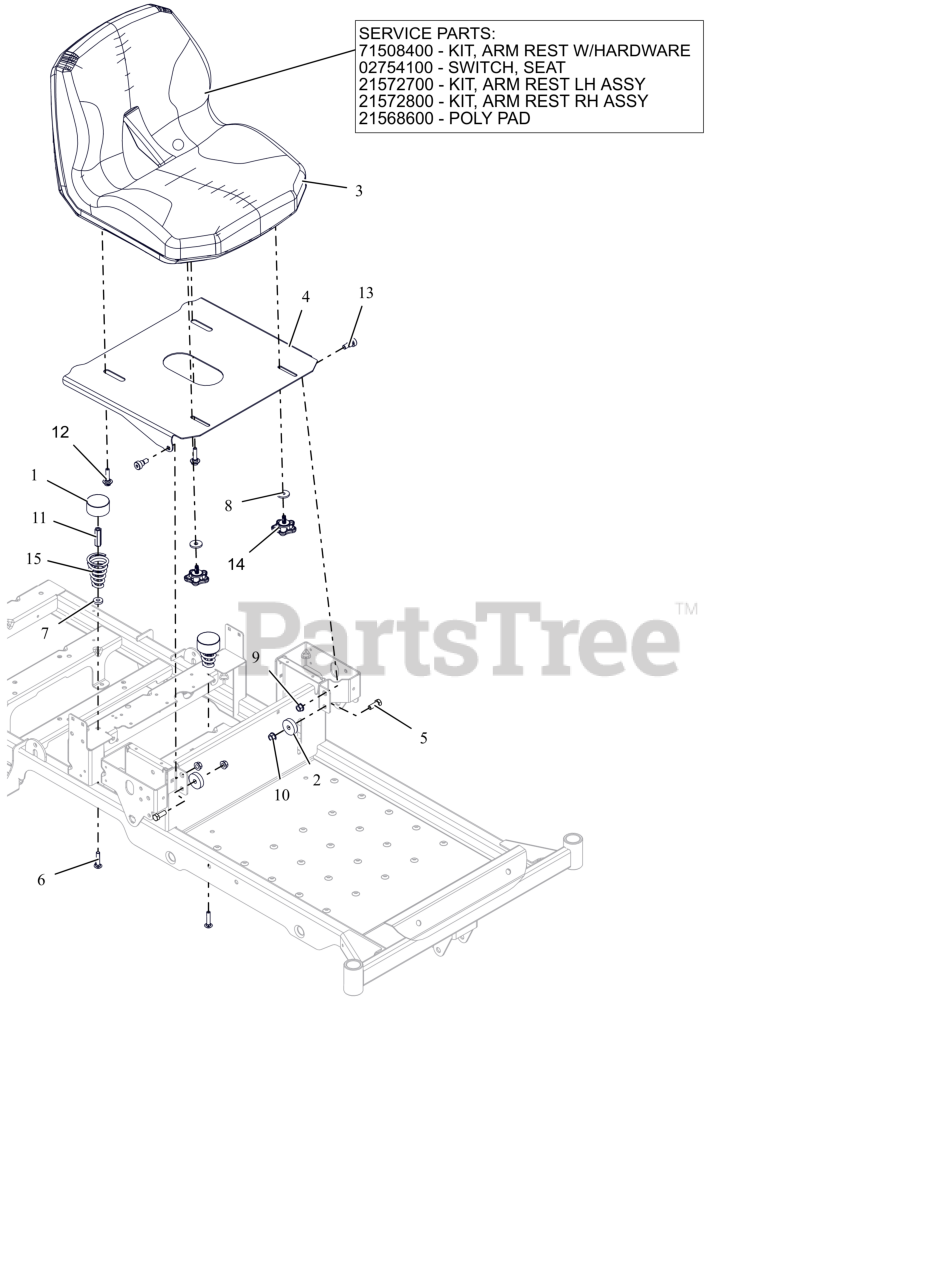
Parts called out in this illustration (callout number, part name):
2	SPACER, .39 X 1.50 X .380
3	SEAT, EDGE 2020
3	KIT- ARMREST - EDGE
3	SWITCH- SNAP MTG N.O.
3	KIT, ARM REST LH ASSY-PADDED
3	KIT, ARM REST RH ASSY-PADDED
3	POLY PAD - ZTX SEAT
4	PLATE- SEAT
5	BLT,HEX .38-16X1.00 G5 ZCC
6	BLT,RHSN .31-18X1.50 G5 ZCC
7	WSHR, FLT .328X.870X.179 ZCC
8	WSHR, FLT .340X1.125X.135 ZCC
9	NUT-LK-TOP-FLG .38-16 ZC120
10	NUT-LK-CTR-FLG .375-16 GF ZCC
11	NUT, COUPLING .31-18X1.75 ZCC
12	BLT, SHLDR .31-18 X .175
13	BLT-SHLDR .38-16X.38 SKH
14	KNOB, WING STUDDED
15	SPRING, SEAT
